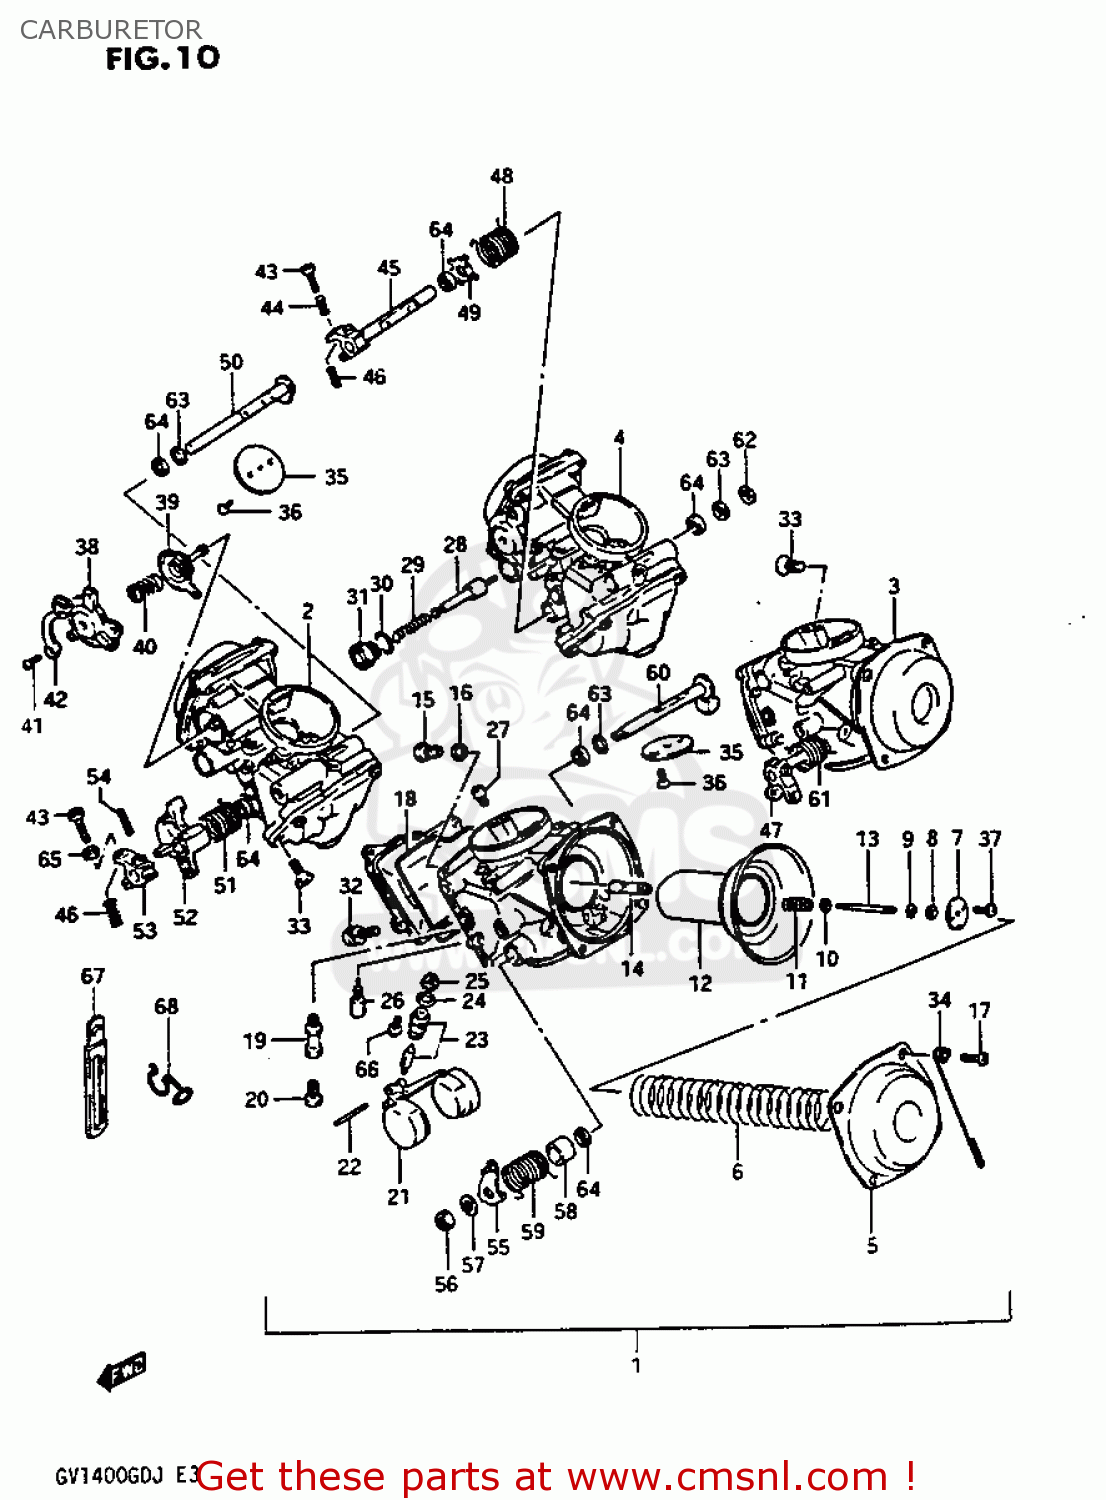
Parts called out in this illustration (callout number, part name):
1	CARBURETOR ASSEMBLY
2	CARBURETOR ASSEMBLY
3	CARBURETOR ASSEMBLY
4	CARBURETOR ASSEMBLY
5	COVER,DIAPHRAGM
6	SPRING,DIAPHRAGM
7	PLATE
8	RING
9	CLIP,NEEDLE
10	WASHER
11	SPRING
12	DIAPHRAGM,CARBURETOR
13	NEEDLE JET
14	JET,NEEDLE
15	SCREW
16	WASHER,NEEDLE NOZZLE
17	SCREW
18	O RING,FLOAT CHAMBER
19	HOLDER,MAIN JET
20	JET,MAIN(105)
21	FLOAT
22	PIN,FLOAT
23	VALVE ASSEMBLY,NEEDLE
24	O-RING,NEEDLE VALVE
25	FILTER
26	JET,PILOT(25)
27	JET,ENRICH
28	PLUNGER
29	SPRING,STARTER PLUNGER
30	O RING
31	HOLDER,GUIDE
32	SCREW
33	SCREW
34	CLIP
35	VALVE,THROTTLE
36	SCREW
37	SCREW
38	COVER
39	DIAPHRAGM ASSY
40	SPRING
41	SCREW
42	BRACKET
43	SCREW
44	SPRING
45	SHAFT,THROTTLE
46	SPRING,THROTTLE SCREW
47	SHAFT,THROTTLE
48	SPRING,THROTTLE VALVE
49	PLATE
50	SHAFT,THROTTLE
51	SPRING
52	LEVER,THROTTLE
53	LEVER,THROTTLE
54	PIN,THROTTLE SHAFT
55	LEVER,THROTTLE
56	NUT
57	WASHER
58	RING
59	SPRING
60	SHAFT,THROTTLE
61	SPRING,THROTTLE VALVE
62	E RING
63	GASKET,THROTTLE SHAFT (NAS)
64	SEAL,THROTTLE SHAFT
65	NUT
66	SCREW
67	CLAMP L:35
68	CLAMP
